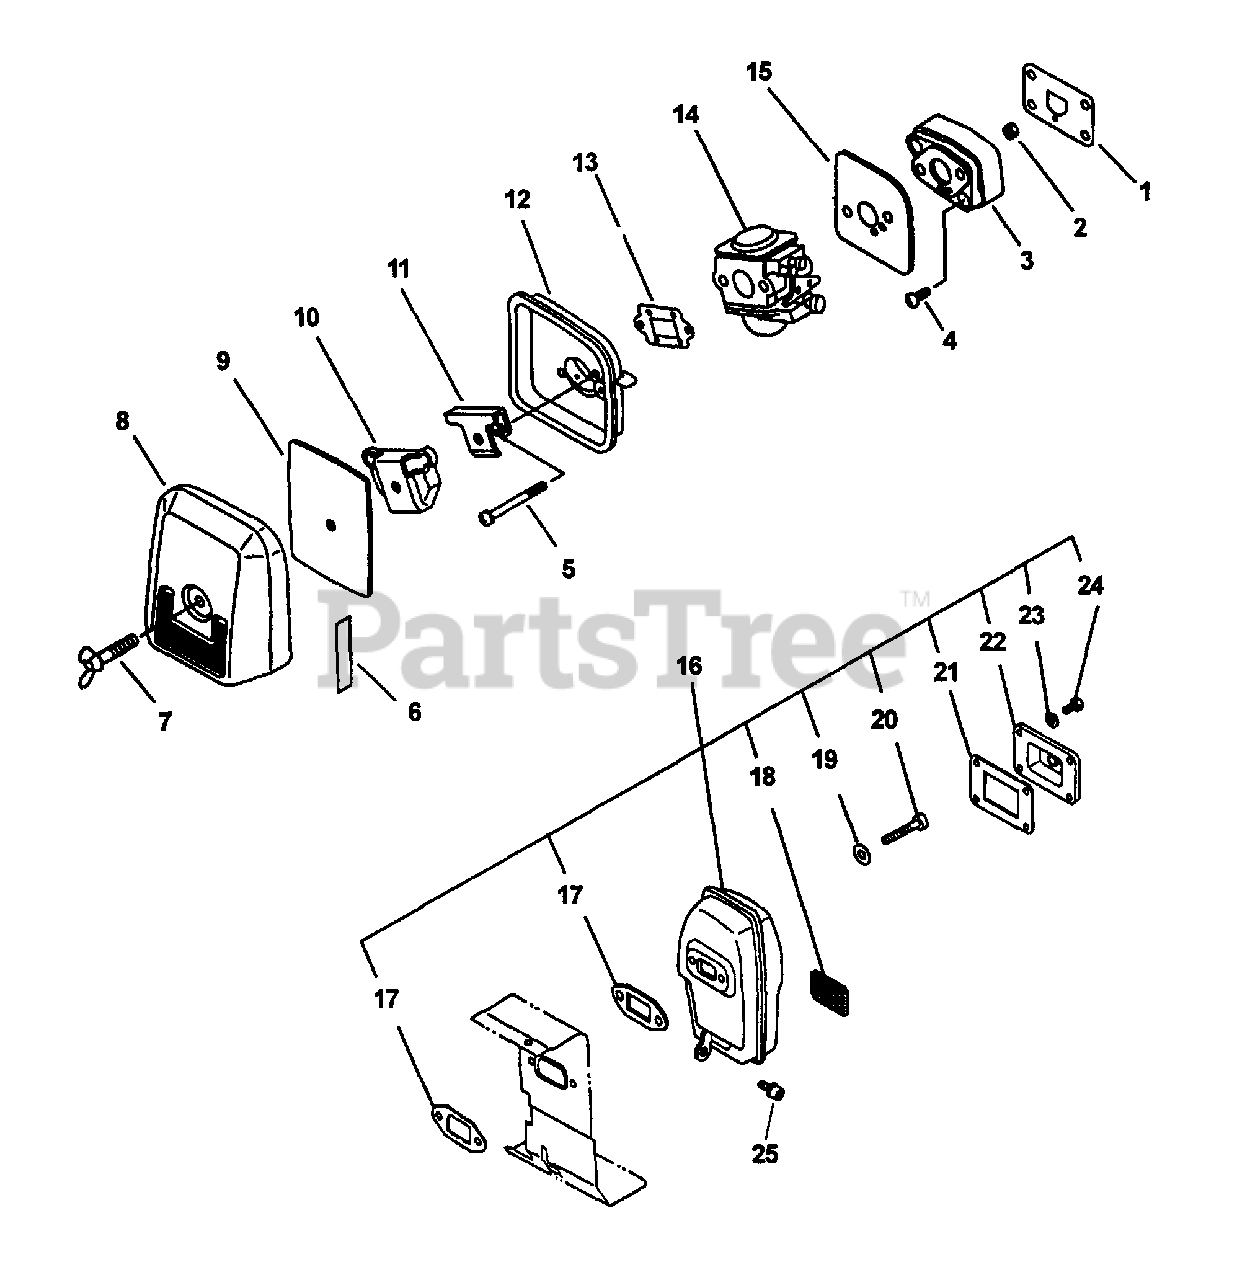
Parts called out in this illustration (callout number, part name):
1	GASKET, INTAKE
3	INSULATOR, INTAKE
4	SCREW - 5X22
5	SCREW - 5X55
6	LABEL - CHOKE
7	THUMBSCREW
8	COVER, AIR FILTER
9	FILTER, AIR - HEAVY DUTY
10	PLATE, PREVENT
11	PLATE, PREVENT
12	AIR FILTER CASE ASSY
14	CARBURETOR WT-417
15	GASKET, INTAKE
16	MUFFLER ASSY
17	GASKET, EXHAUST
18	SCREEN, SPARK ARRESTOR
19	WASHER - 5
20	SCREW - 5X60
21	GASKET, EXHAUST
22	GUIDE, EXHAUST
23	LOCKWASHER - 4
24	SCREW - 4X12
25	SCREW - 5X16
